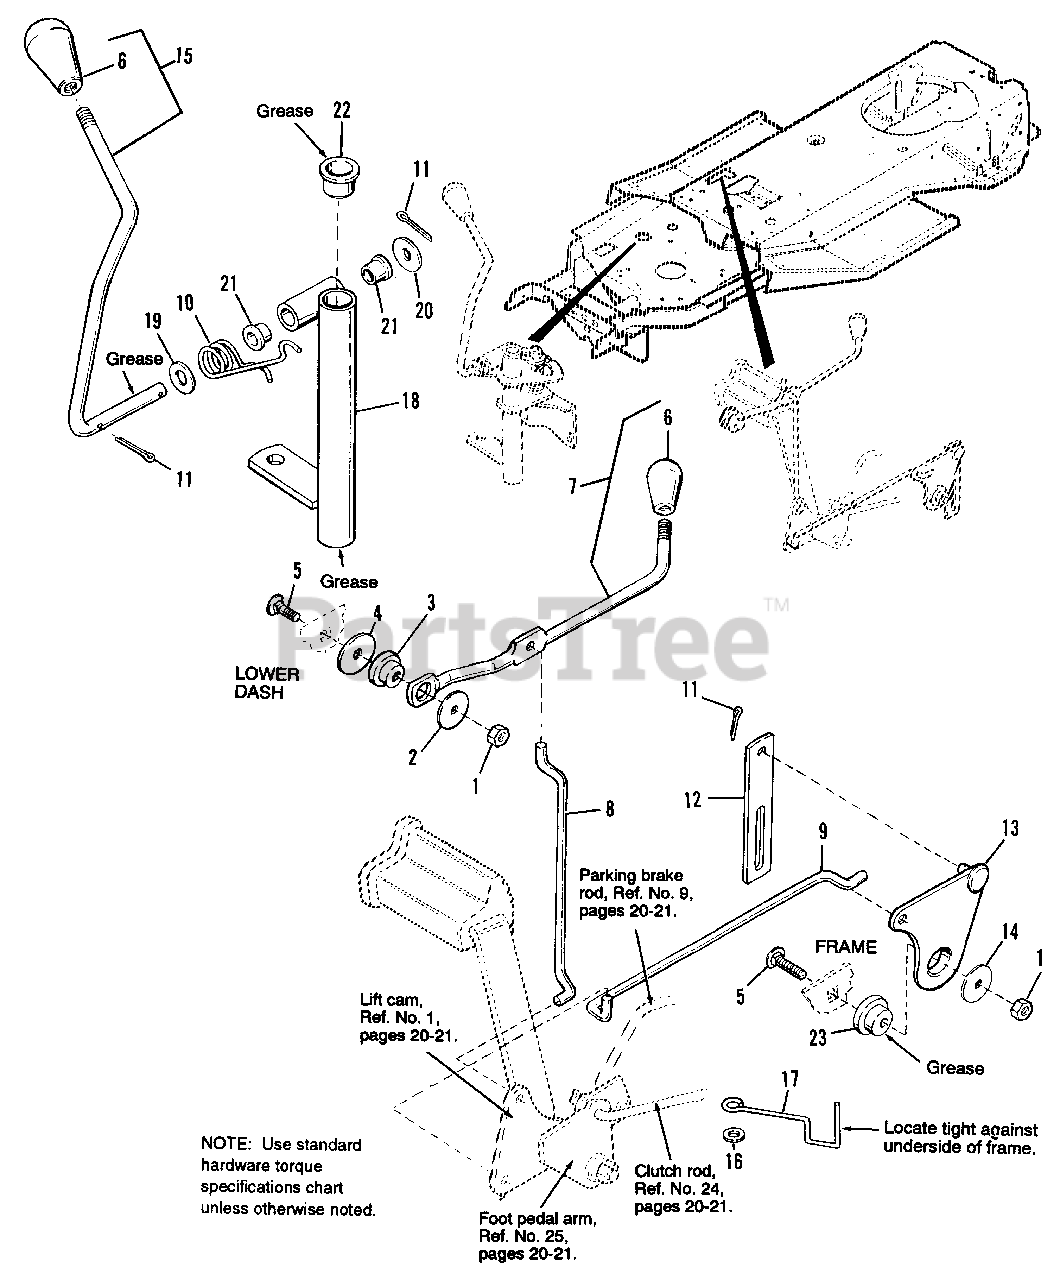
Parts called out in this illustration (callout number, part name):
1	NUT, Hex, Esna, Lock, 5/16-18
2	WASHER, Plain, 5/16
3	SPACER, Special
4	WASHER, Plain, 13/32 x 1-1/5 x 1/8
5	CARRIAGE BOLT, 5/16-18 x 1-1/2
6	KNOB, Plastic
7	ROD, Lift Handle (Incl. Ref. No. 6)
8	LINK, Lift, Upper
10	SPRING, Torsion
11	COTTER PIN, 3/32 x 3/4
12	LINK, Lift, Upper Transport
13	CAM, Lift Assy.
14	WASHER, Plain, 21/64 x 1-1/4 x 5/64
15	LEVER, Shift (Inc. Ref. No. 6)
16	WASHER, 5/16
17	BELT STOP
18	SHIFT LEVER ASSY.
19	WASHER, Plain, 17/32
20	WASHER, Plain, 33/64
21	BUSHING, Plastic
22	BUSHING, Nylon
23	SPACER, Special
